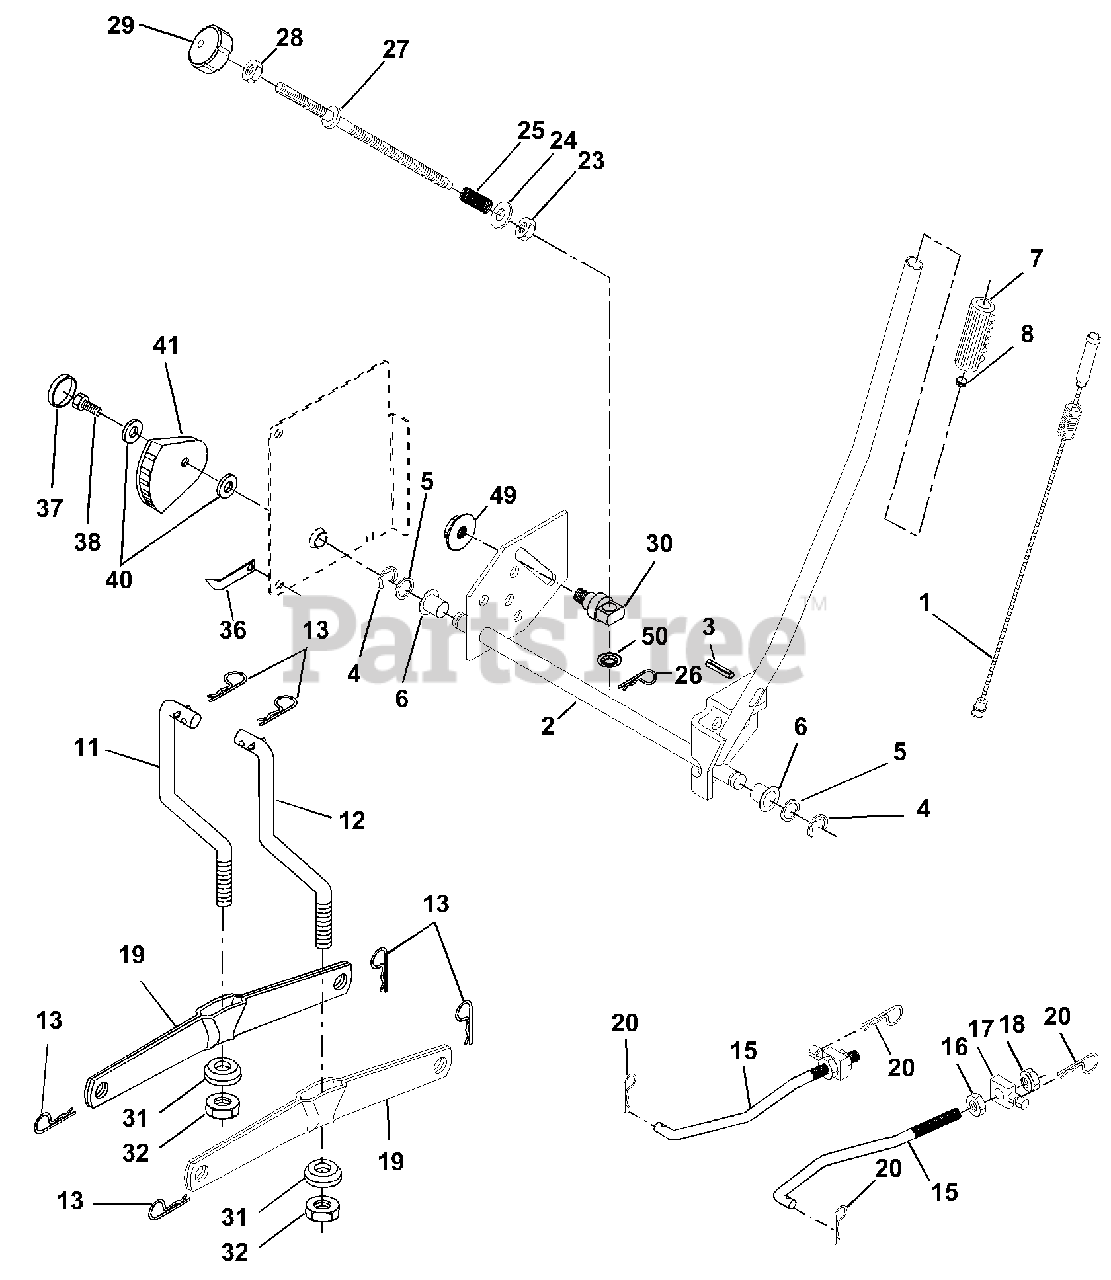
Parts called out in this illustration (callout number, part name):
1	Wire Asm Inner/Sprg W/plunger
2	Shaft Asm Lift RH w/Inf
3	Pin Groove
4	E Ring #5133-62
5	Washer 21/32 X 1 X 21 Ga
6	Bearing Nylon Blk 629 Id
7	Grip Handle
8	Button Plunger
11	Link Lift LH Fixed Length
12	Link Lift RH Fixed Length
13	Retainer Spring
15	Link Front
16	Nut Jam Hex 1/2-13 Unc
17	Trunnion Blk Zinc
18	Nut Lock w/Wsh 1/2-13unc
19	Arm Suspension Rear
20	Retainer Spring
23	Nut Special
24	Washer 13/32 X 5/8 X 16 Ga
25	Spring
26	Retainer Clip
27	Rod Adj Lift
28	Nut Hex Jam 3/8-16 Unc
29	Knob Inf 3/8-16 Unc Blk W/sym
30	Trunnion Infin Height
31	Bearing Pvt Lift
32	Nut Crownlock 3/8 - 24
36	Pointer Height Indicator
37	Plug Hole Blk 1.485/1.515 Dia.
38	Screw 5/16-18 x 1
40	Washer 11/32 x 1-1/2 10 Ga.
41	Indicator Height STLT
49	Nut Hex Flange Lock
50	Nut PUsh Phos & Oil
